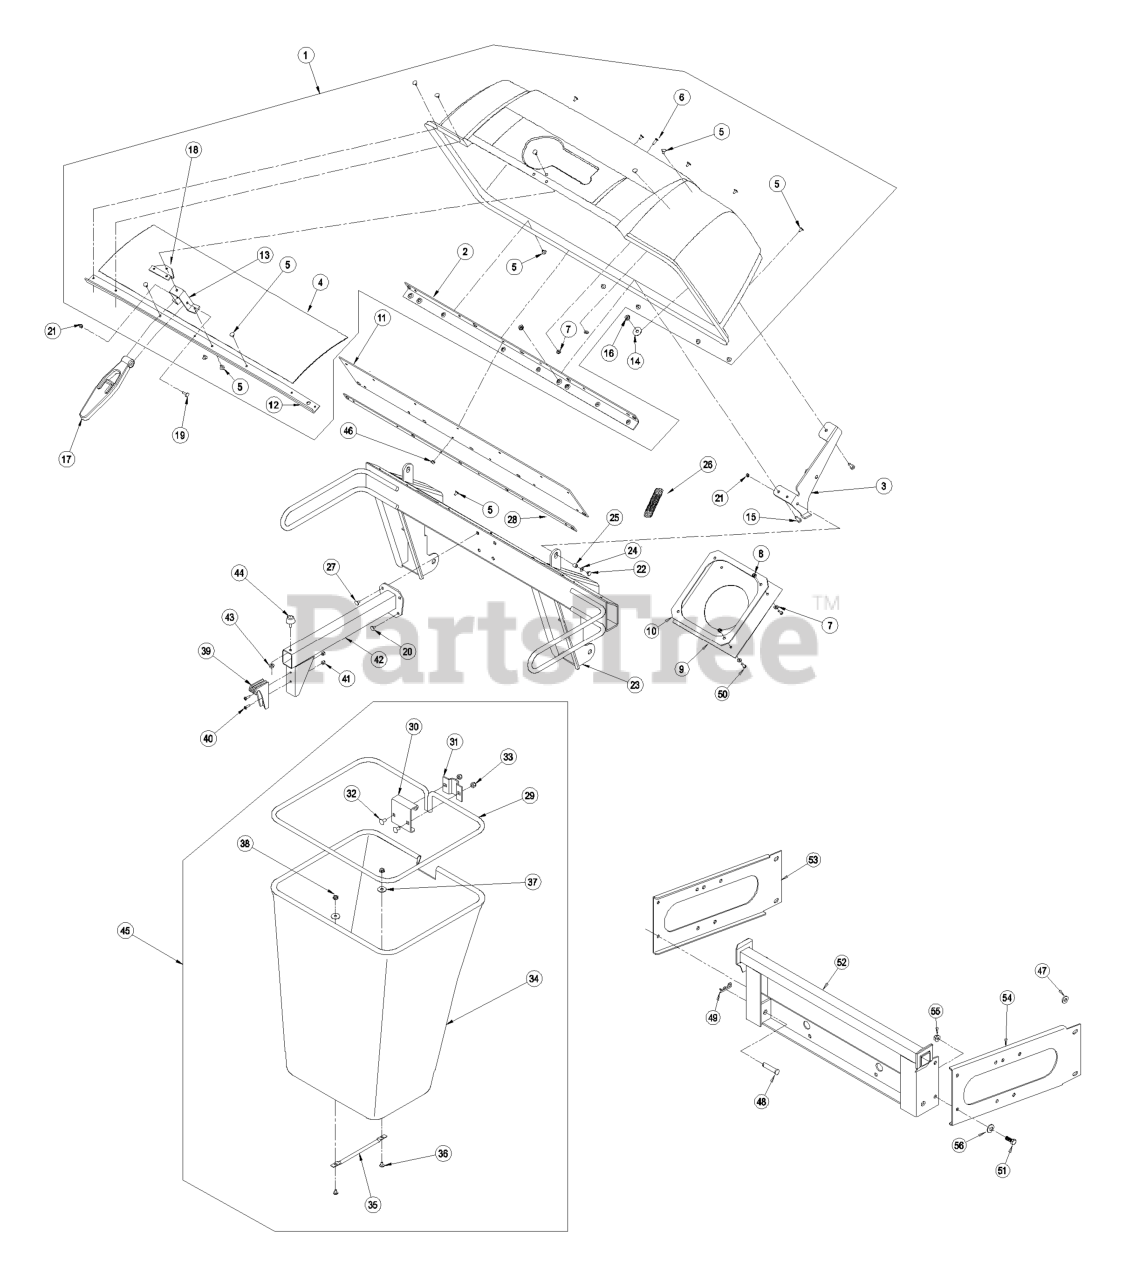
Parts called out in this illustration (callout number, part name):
1	ASM, HOOD
2	STIFFENER-BAGGER, TOP
4	SCREEN-BAGGER
5	RIVET-BLIND
6	SCREW-HEAD, TRUSS
7	WASHER-FLAT
8	NUT-LOCK, NI
9	SEAL-CHUTE
10	CLAMP-SEAL
11	SEAL-HOOD
12	SUPPORT-SCREEN
13	ANCHOR-LATCH
15	SCREW-HH
18	REINFORCEMENT-LATCH
19	SCREW-HH
20	SCREW-HSBH
21	NUT-LOCK, NI
22	SCREW-HH
23	UPRIGHT-BAGGER
24	WASHER-FLAT
26	SPRING-EXTENSION
27	SCREW-HH
28	PLATE-BACKING
29	FRAME-BAG
30	HANGER-BAG
32	BOLT-CARR
33	NUT-LOCK, NI
35	HANDLE-BAG
36	BOLT-CARR
38	NUT-LOCK, NI
40	SCREW-PPH
42	SUPPORT-BAG
46	NUT-LOCK, SIDE
48	PIN-CLEVIS
49	PIN-COTTER
50	SCREW-PPH
51	SCREW-HH
52	MOUNT-BAGGER
53	BRACKET-FRAME, LH
54	BRACKET-FRAME, RH
55	NUT-HHF, WHIZ
56	WASHER-BELLEVILLE
